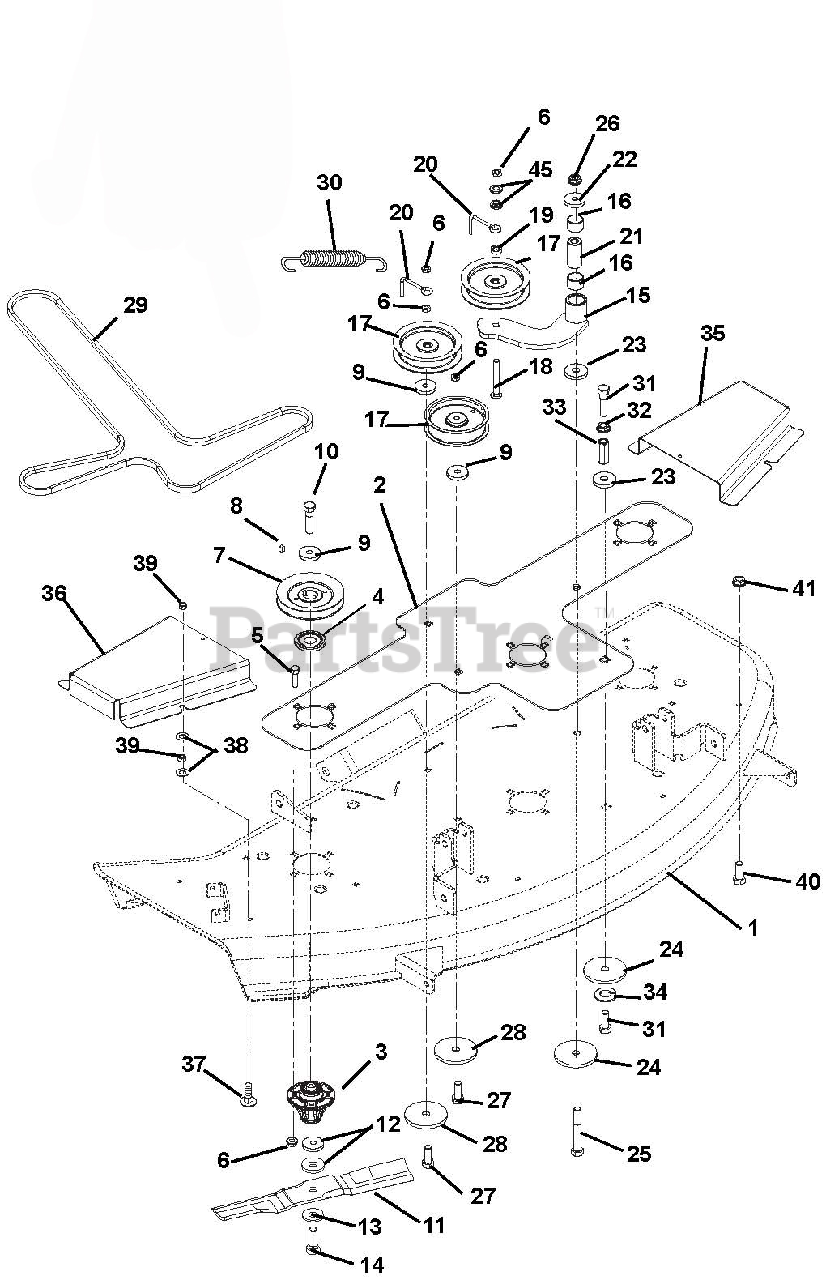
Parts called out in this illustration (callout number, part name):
1	WELDMENT, 50" DECK
2	50" DOUBLER PLATE
3	SPINDLE ASSEMBLY
3	PULLEY, SPINDLE
4	DUST CAP
5	@BLT-RDHDSQNK .38-16X1.25 G5YZ
6	@NUT-LK-NYL-FLG .38-16 YWZC
7	SHEAVE, 4.75 DIA A-SECTION
8	KEY, SQ .25 X .38 X .25
9	WSHR,FLT STL.406X1.50X.245YWZC
10	BLT-HEX .38-16X1.0 GR8 YZ EP30
12	WSHR-FLT .640X1.75X.250 YWZC
13	WSHR-BLVL .669X1.535X.138
14	BLT-HEX .62-18X1.75 GR8 YWZC
15	WMT, IDLER ARM
16	BRG, 1.00 X 1.12 X .75
17	IDLER, FLAT .38X4.00X1.06
18	@BLT-RDHDSQNK .38-16X3.50 G5YZ
19	BSHG-SLV .391X.688X.52 PM
20	BELT FINGER
21	BSHG, SPCR .502X.997X2.03 PM
22	WSHR-FL-STL.511X1.441X.125 YWZ
23	WSHR-FL-STL .515X1.625X.250 YZ
24	WASHER, FLAT .531X3.000X.25
25	@BLT-HEX .50-13X3.50 GR5 YWZC
26	@NUT-LK-TOP-FLG .50-13 YWZC
27	@BLT-HEX .38-16X2.75 GR5 YWZC
28	WSHR-FL-STL .469X2.00X.25 YWZC
29	V-BELT, A-WRAPPED
30	EXTENSION SPRING
31	@BLT-HEX .50-13X1.25 GR5 YWZC
32	NUT-SPNLK-FLG .50-13 YWZC
33	NUT, COUPLING 1/2-13X1.75 YWZC
34	@WSHR-LK .50X.125 REG YWZC
35	BELT COVER, LEFT
36	BELT COVER, RIGHT
37	@BLT-RHDSHSQNK.31-18X1.25 G5YZ
38	@WSHR-FL-STL.38X.875X.083 YWZC
39	@NUT-LK-NYL-FLG .31-18 YWZC
40	@BLT-HEX .31-18X.75 GR5 YWZC
41	@NUT-SPNLK-FLG .312-18 YWZC
45	BSHG-FLG .406X.88X.270X.140
